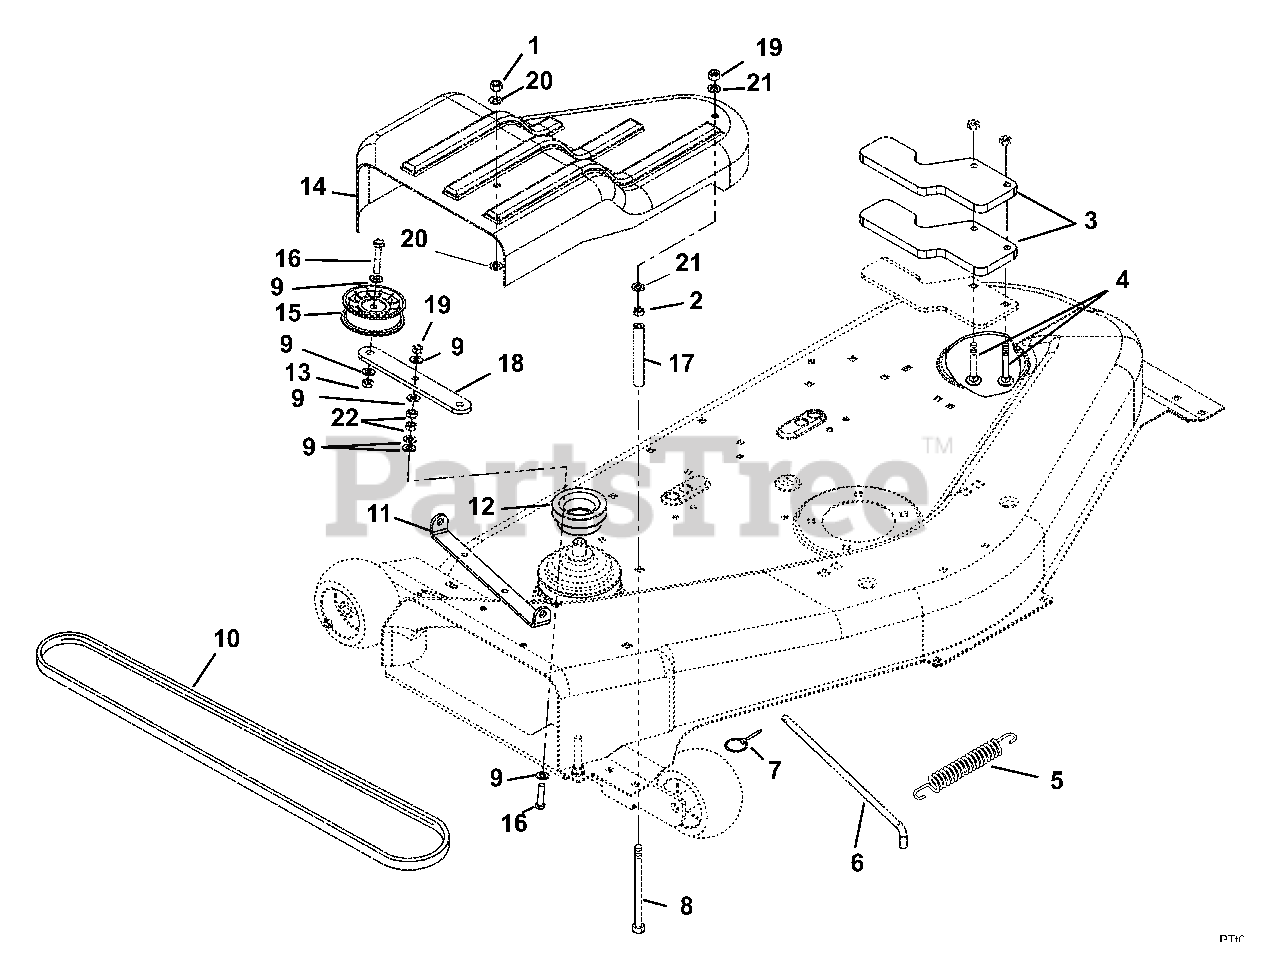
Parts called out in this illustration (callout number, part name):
1	@NUT-LK-NYL .250-20 YWZC
2	@NUT-LK-CTR .31-18 YWZC
3	COUNTERWEIGHT
4	@BLT-RDHDSQNK .31-18X1.75 G5YZ
5	SG-TENS .069X.62X3.50 WLD20
6	ROD-MOUNTING
7	PIN-KLIK 1.000X.188X1.25 YWZC
8	BLT-HEX .31-18X6 FLTHD GR5 YZC
9	@WSHR-FL-STL.344X.688X.065YWZC
10	V-BELT, HA-RAW EDGE
11	BRACKET, CHUTE PIVOT
12	PULLEY-DRIVER 3.00"
13	@NUT-SPNLK-FLG .312-18 YWZC
14	COVER-GRASS PUMP BELTS
15	IDLER-FLAT 3.00X.38
16	BLT-HEX .31-18X1.75 FLTHD YWZC
17	SPACER .334X.500X4.625
18	BRACKET-TENSION ARM
19	@NUT-LK-NYL .312-18 YWZC
20	WSHR-FL-STL .281X1.000X.063
21	WSHR-FL-STL .347X1.254X.048YWZ
22	NUT- JAM .312-18 YWZC
